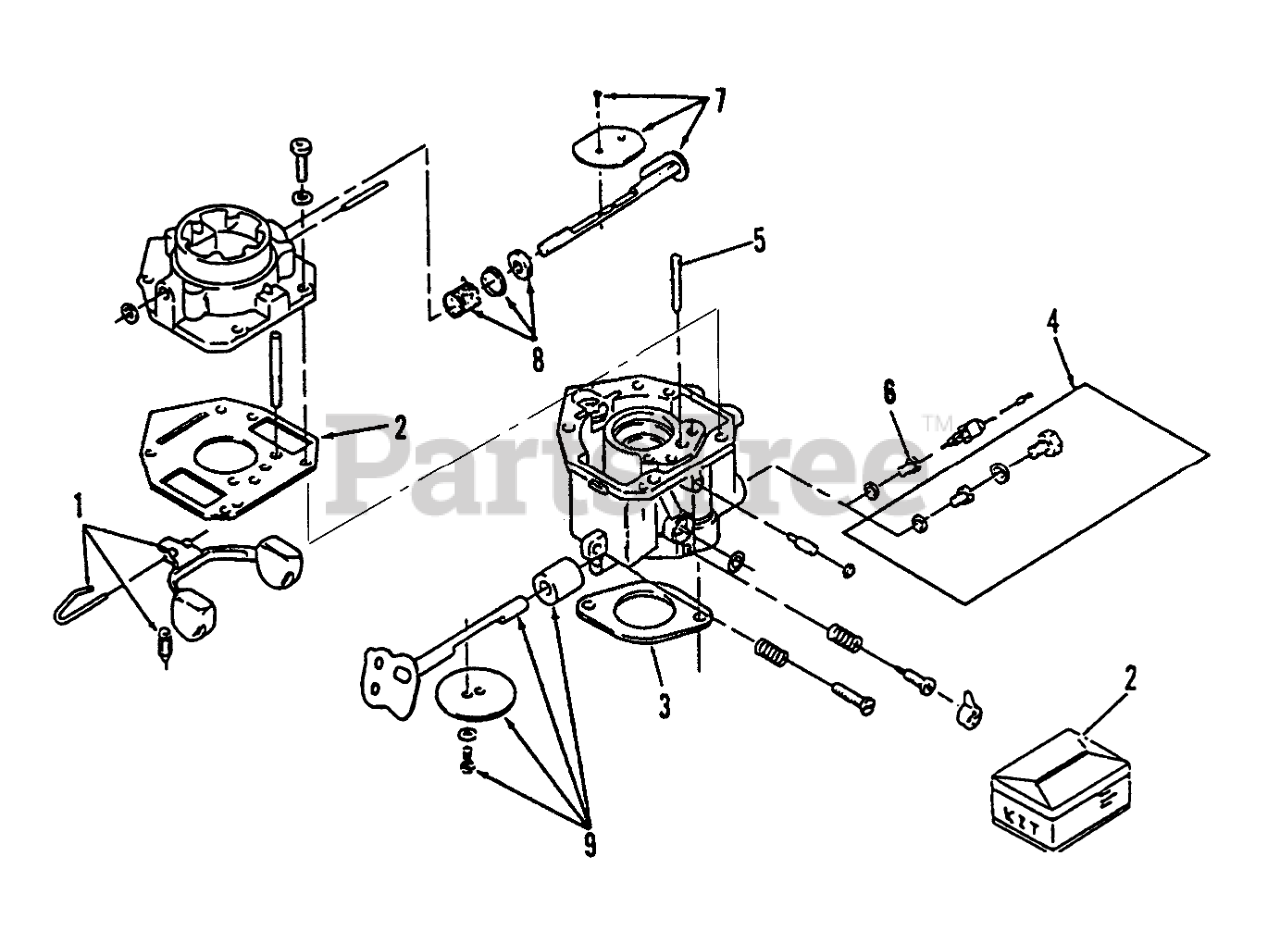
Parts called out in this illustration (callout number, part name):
1	Kit-Float (Incl. Float, Pin, & Valve)
2	Kit-Repair (Incl. Screw & Plug Package,Gasket Package,Float Valve, Idle Adjustment Needle & Spring, Mounting Gaskets, & Idle Limit Cap)
3	GASKET-CARBURETOR
4	FIXED-JET PKG
5	Idle Jet
6	POWER JET
7	Kit-Choke Shaft (Incl.Choke Valve,Valve Screw-Set,& Air Filter)
8	Kit-Choke Lever (Incl.Choke Lever Ring, Choke Spring, & Choke Collar)
9	Kit-Throttle Shaft (Incl. Valve Screw-Set, Air Filter, & Throttle Valve)
